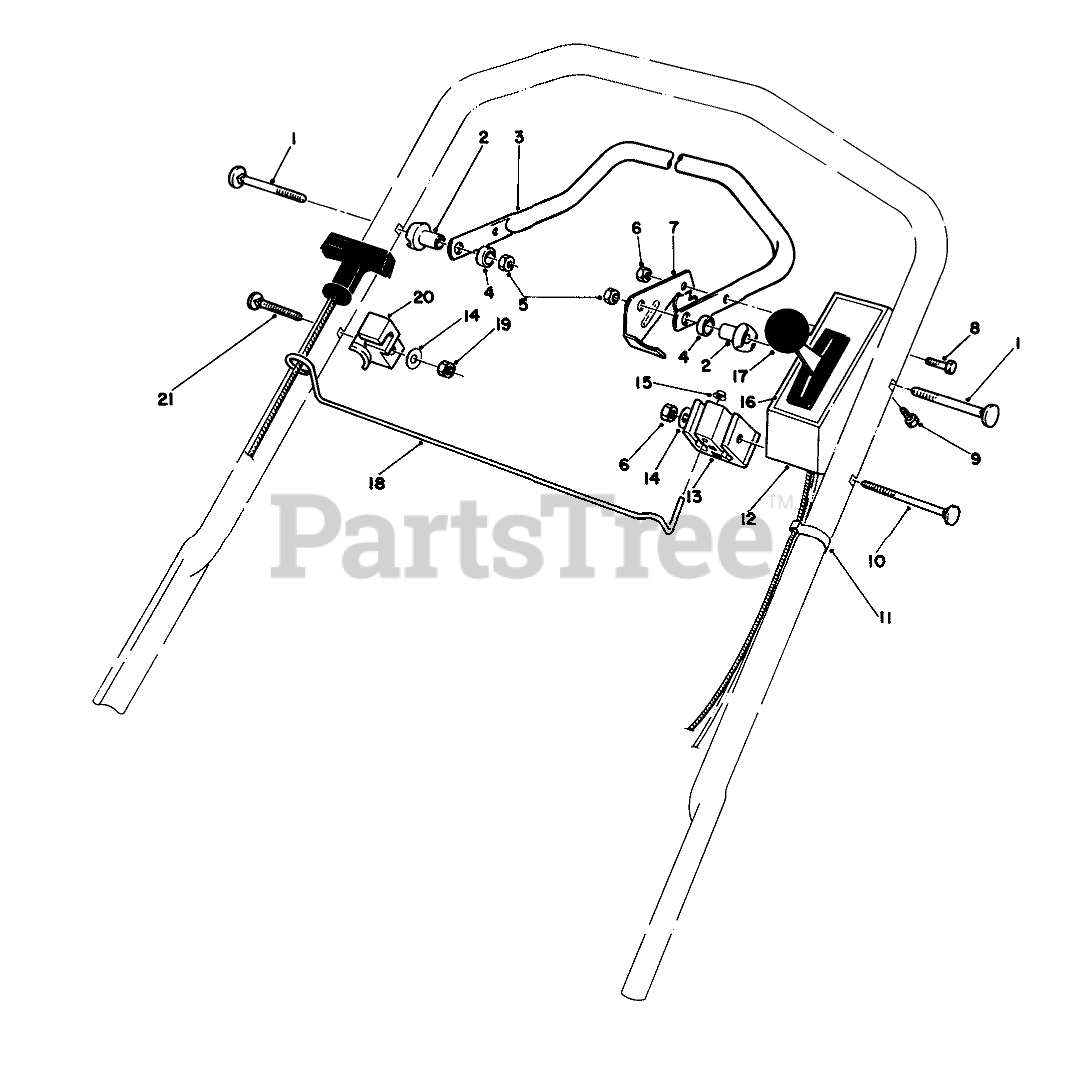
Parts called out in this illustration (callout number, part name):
1	5/16-18 X 2 HNDLE SCREW
2	SPACER-SUPPORT
3	Bar-Control
4	SPACER-NYLON
5	NUT-LOCK, NI
6	NUT-LOCK, NI
7	LEVER-CONTROL
8	SCREW-HH
9	SCREW-HWHTF
10	HANDLE SCREW
11	BOWDEN CLIP
12	Cover-Control (Incl. Ref. #16)
13	SUPPORT-CABLE
14	WASHER-FLAT
15	NUT-SPEED
16	Decal-Control Cover
17	THROTTLE CONT-SERVICE
18	ROPE ROD PLATED
19	NUT-HEX
20	ROD CATCH
21	SCREW-HANDLE
